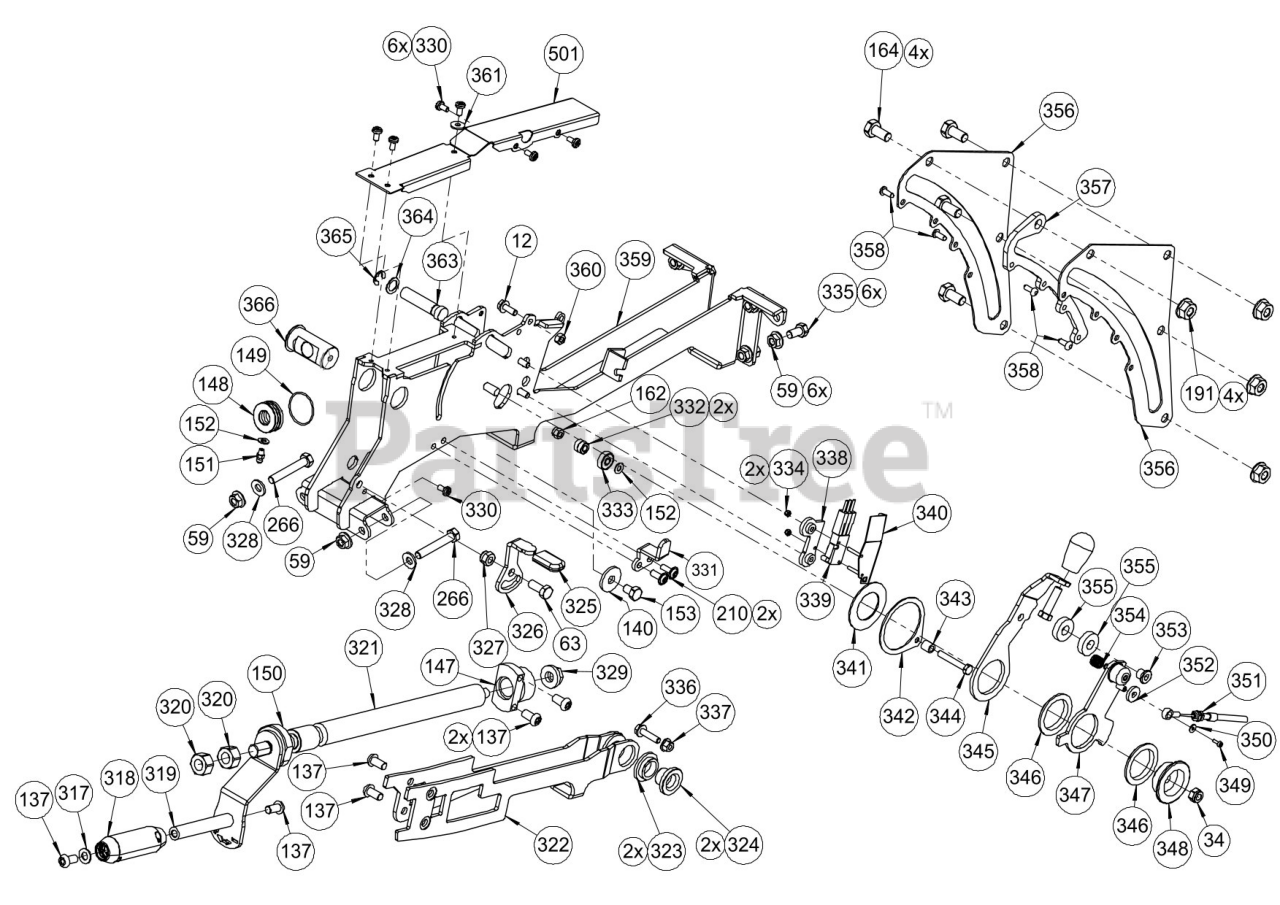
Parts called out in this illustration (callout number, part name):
12	NUT, FLG SLF LK M6X16
34	NUT, LK-NYL M8 DIN 985 8 ZCC
59	NUT, FLG SLF LK M8 CL 8 ZCC
63	BLT, HEX M8X20 DIN 933 8.8
137	TORX BHCS M8X16 8.8
140	WSHR, FLT M9 X M28 X M3 ZCC
147	NUT, ADJUSTING SPINDLE
148	BRG,BALL AXIAL-DP GROOVE-15X32X12
149	O - RING 32X1,5
150	HOUSING, BEARING/GREASE
151	FITTING, GREASE
152	WSHR, FLT M6 X M12 X M1 DIN 988
153	BLT, HEX M8X12 DIN 933 8.8 ZCC
162	NUT, HEX LK-NYL M6 DIN 982 8 ZCC
164	BLT, HEX M10X20 DIN 933 8.8 ZCC
191	NUT, FLG SLF LK M10 CL 8 ZCC
210	TORX FBHCS M6X16-8.8
266	BLT, HEX M8X 45 DIN 931 8.8 ZCC
317	WSHR, FLT A M8.4 DIN 125 ZCC
318	KNOB, CRANK HANDLE
319	HANDLE, CRANK
320	NUT, JAM M14X1.5 ZCC
321	SPINDLE, ENGAGEMENT ADJUSTING
322	BRACKET, ENGAGEMENT SPINDLE
323	BUSHING, COLLAR
324	BUSHING, LIFT ARM
325	CAP, LOCKING PLATE
326	HANDLE, LOCKING
327	NUT, LK-NYL M8X1.25 DIN 982 8 ZCC
328	WSHR - BLVL M8 DIN 6796
329	WSHR, FLTT M11.3X24X4
330	TORX SHCS M5X10 8.8 ZCC
331	REST, HANDLE
332	BRG,BALL 6X13X5 686-ZZ
333	BRG,BALL 626-2RS DIN625(6X19X6)
334	NUT, LK-NYL M3 DIN 985 5 ZCC
335	BLT, HEX M8X16 DIN 933 8.8 ZCC
336	BLT, FLG M6X25 DIN 6921 8.8 ZCC
337	NUT, FLG-LK-NYL M6
338	BRACKET, SWITCH MOUNTING
339	SWITCH, SAFETY
340	COVER, SWITCH
341	WSHR, FLT M32 X M54 X M1.5
342	DISC, RELEASE
344	BLT, HEX M6X40 DIN 931 8.8 ZCC
345	KIT, ENGAGEMENT LEVER
346	BUSHING, ENGAGEMENT LEVER
347	ASSY, LATCHING LEVER
348	BUSHING, FLANGE
349	SCR, SKH M3X8 DIN ISO 4762 8.8
350	WSHR, FLT M3.2 DIN 9021 ZCC
351	CABLE, PTO
352	WSHR, FLT M6.4 DIN 7349 ST ZCC
353	SPECIAL NUT M6
354	SPRING, COMPRESSION
355	WASHER, SPRING
356	PLATE, CHEEK
357	PLATE, STRUT
358	RVT 5X12 A2/A2
359	WLDMT, ENGAGEMENT
360	NUT-STD M6-1.0 ZCC
361	WSHR, FLT M5.3 DIN 9021-ST ZCC
363	BOLT, LOCKING
364	WSHR, FLT M12 DIN 988
365	E-RING 1X.2 DIN 6799
366	TRUNNION, HOC SPINDLE
501	COVER, CONTROLS (W/ DECAL)
